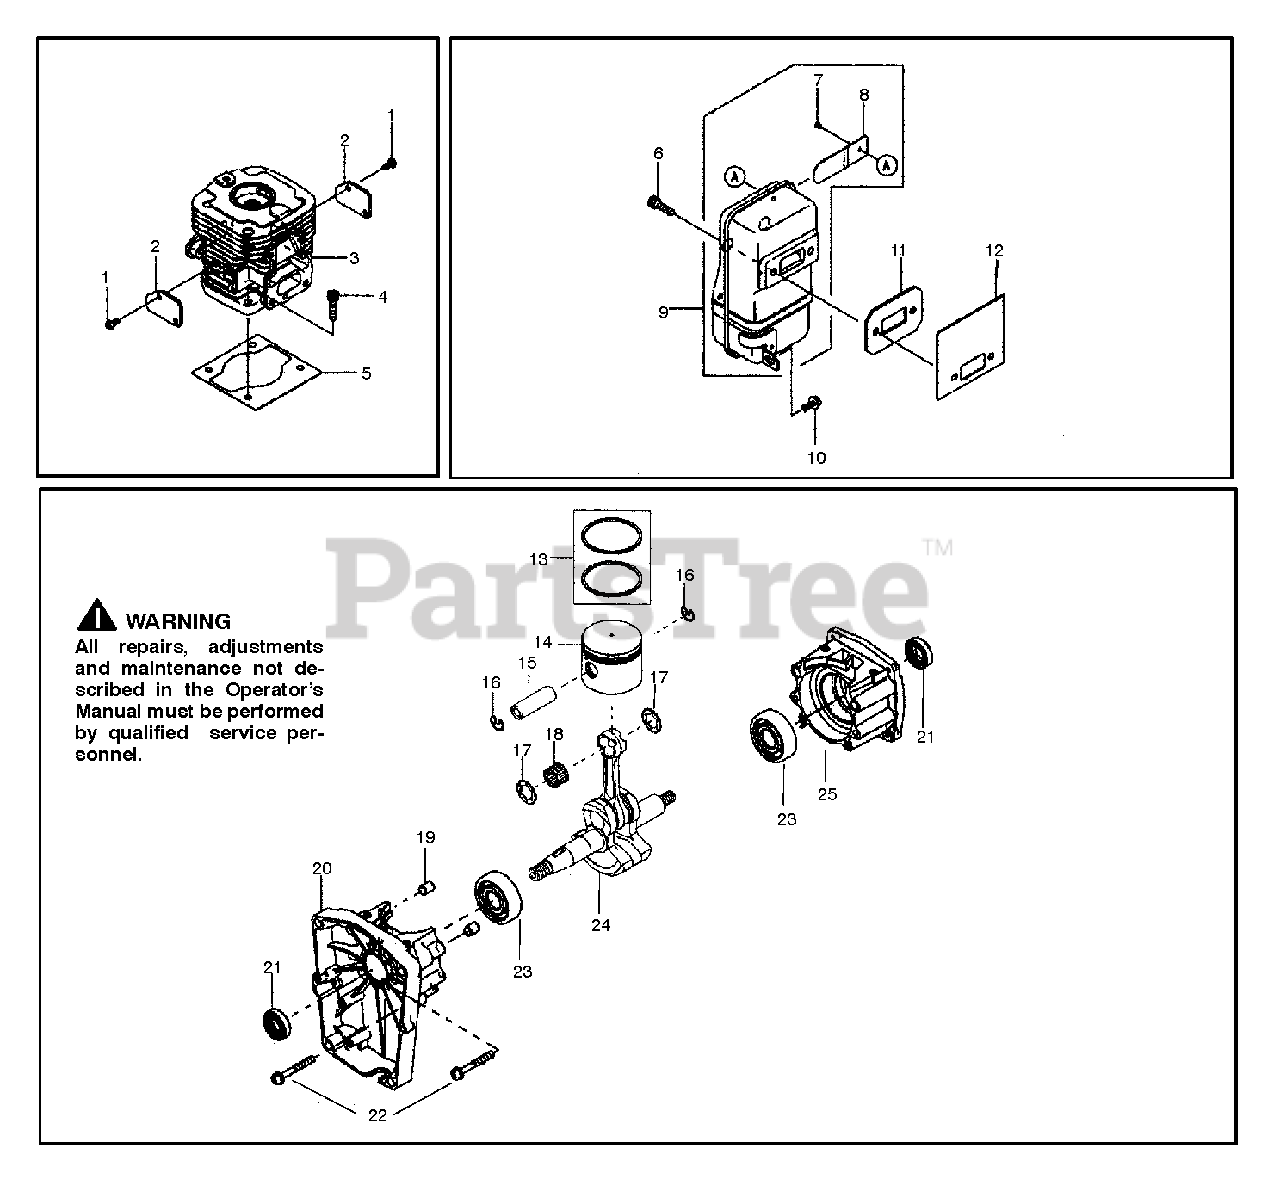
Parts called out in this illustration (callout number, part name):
3	CYLINDER ENGINE
4	BOLT SOCKET 5 X 20
5	GASKET CYLINDER BP406
6	BOLT SOCKET 6 X 20
8	ARRESTER SPARK
9	MUFFLER ASSY
10	SCREW PAN WSP 5 X 14
12	GASKET OTHER - GAS L/G PARTS
13	RING SET PISTON
14	PISTON ENGINE
15	PIN PISTON
16	SNAP RING
18	BEARING SMALL END
20	CRANKCASE
21	SEAL OIL ISCD-15-25-7-F
22	SCREW PAN WSP 5 X 40
23	BEARING BALL 6302C3
24	CRANKSHAFT ASSY
25	CRANKCASE
